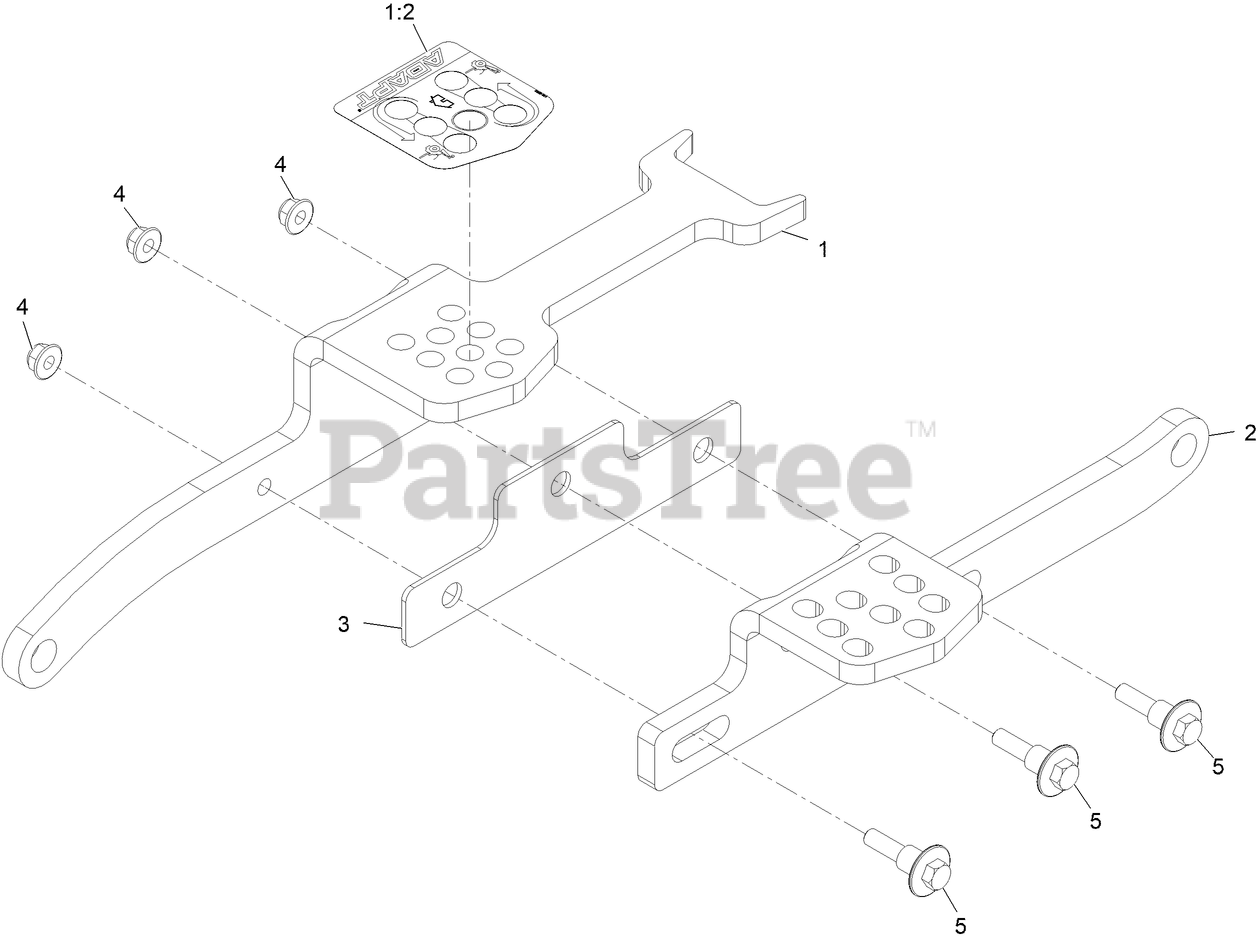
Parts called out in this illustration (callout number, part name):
1	ASM- Link W/Decal
1:2	Decal- Rake
2	Link- Deck Lift Rear
3	PLATE- SLIDE
4	NUT-HF, NI
5	SCREW-SHOULDER, HHF
